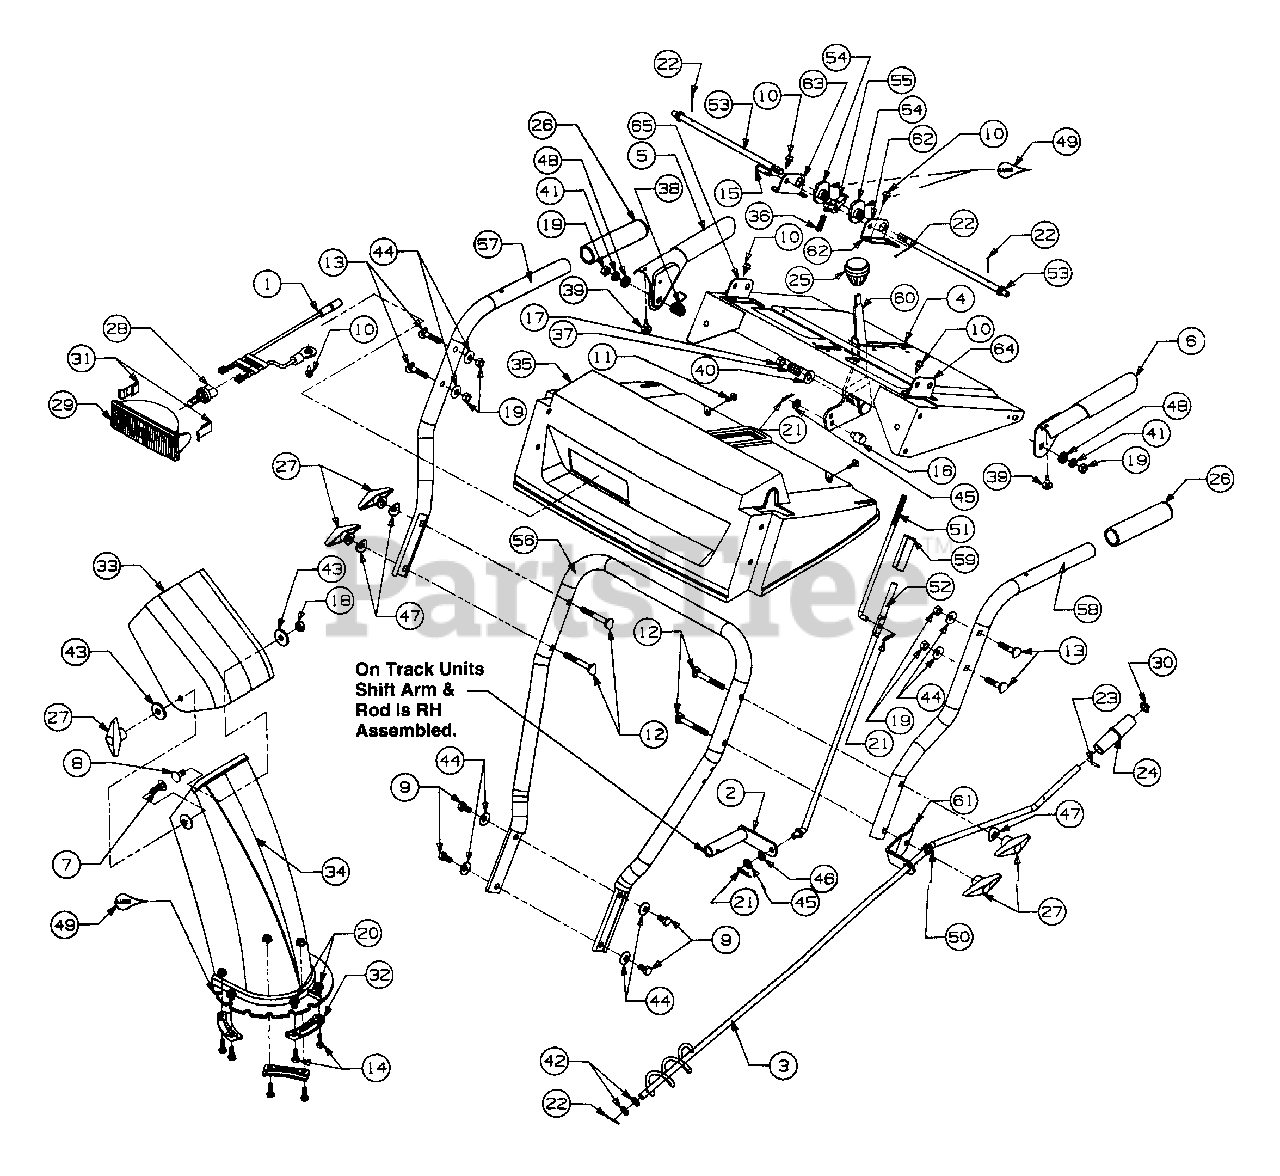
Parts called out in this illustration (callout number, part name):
1	Harness, Light
3	Crank, Chute
6	Handle, Engagement L.H.
7	Screw, Carriage
8	Bolt, Carriage
9	Hex Screw
10	Hex Screw
11	Screw, Hex
12	Bolt, Curved Carriage
13	Bolt, Curved CArriage
14	Hex Cap Screw
15	Pin, Clevis
16	Ferrule, Engagement
17	Hex Lock Nut
18	Nut, Hex
19	Nut, Hex
20	Nut, Lock, Hex, Flanged
21	Pin, Cotter
22	Pin, Cotter
23	Roll Pin
24	Knob, Chute Crank
25	Knob, Shift
28	Lamp, Halogen
29	Housing, Lamp, Lens Ass'y.
30	Cap, Push
31	Clip, Retaining
32	Chute, Flange Keeper
33	Chute, Upper 5.0 Dia.
34	Lower Chute, 5" Dia. Plastic
35	Panel, Handle
36	Spring
37	Spring
38	Spring
39	Bumper
40	Washer, Bell
41	Lock Washer
42	Flat Washer
43	Washer
44	Washer, Bell
45	Washer, Flat
46	Washer
47	Washer, Saddle
48	Washer
49	Lubricant
50	Bushing, Plastic
51	Rod, Shift, Upper
52	Rod, Shift, Lower
53	Rod, Cam
54	Cam Handle Lock
55	Pawl Handle Lock
59	Connector, Clutch Rod
60	Shift Handle
